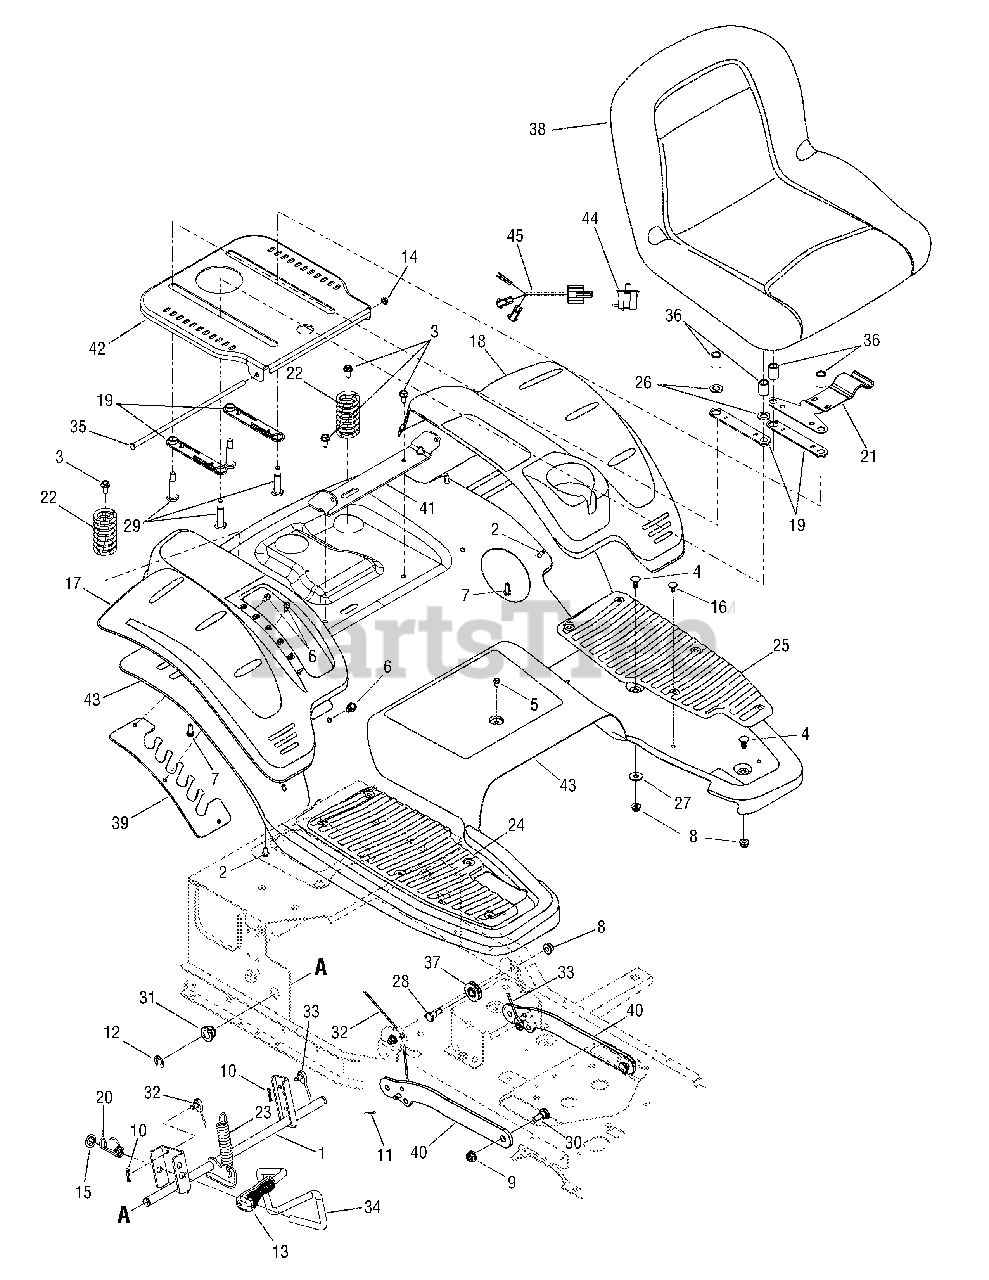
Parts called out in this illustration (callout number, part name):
2	Screw, Hex Wash Hd. H/L, 1/4-15 x .5
3	Screw, Hex Wash Hd. Tapp, 5/16-18 x .75
4	Screw, Carriage, 5/16-18 x 75
5	Screw, Hex Wash Hd. Tapp, 1/4-20 x .5
6	Screw, Hex Wash Hd. Tapp, 5/16-12 x .75
7	Screw, Hex Wash Hd. Tapp, 1/4-15 x .75
8	Nut, Hex Flange Insert Lock, 5/16-18 GrF
9	Nut, Hex Flange Insert Lock, 3/8-16 GrF
10	Pin, Internal Cotter
11	Pin, Cotter, 3/32 x 1.0
12	E-ring, .625 Shaft
13	Grip, Handle
14	Nut, Speed, .3125 Dia.
15	Nut, Speed, .5
16	Clip, Ratchet
17	Cover, Rear Fender RH
18	Cover, Rear Fender LH
19	Spacer, Seat Adjust
20	Spring, Lift Handle Torsion
21	Spring, Seat Adjust
22	Spring, Compression, 1.71 x 3.25 x .23
23	Spring, Extension, .865 x 4.68
24	Pad, Foot RH
25	Pad, Foot LH
26	Washer, Flat, .535 x .93 x .09
27	Washer, Flat, .344 x 1.0 x .063 HT
28	Bolt, Shoulder, .496 x 2.5:3/8-16
29	Bolt, Shoulder, .496 x 1.525:3/8-16
30	Bolt, Shoulder, .5 x .27:3/8-16
31	Bearing, Hex Flange,
32	Cable, Lift, 16.16 Lg
33	Cable, Lift, 16.16 Lg
34	Handle, Lift
35	Rod, Seat, 5/16 x 11.62
36	Spacer, .51 x .75 x 1.0
37	Pulley, Roller
38	Seat, High Back
45	Harness, Seat Switch Jumper
